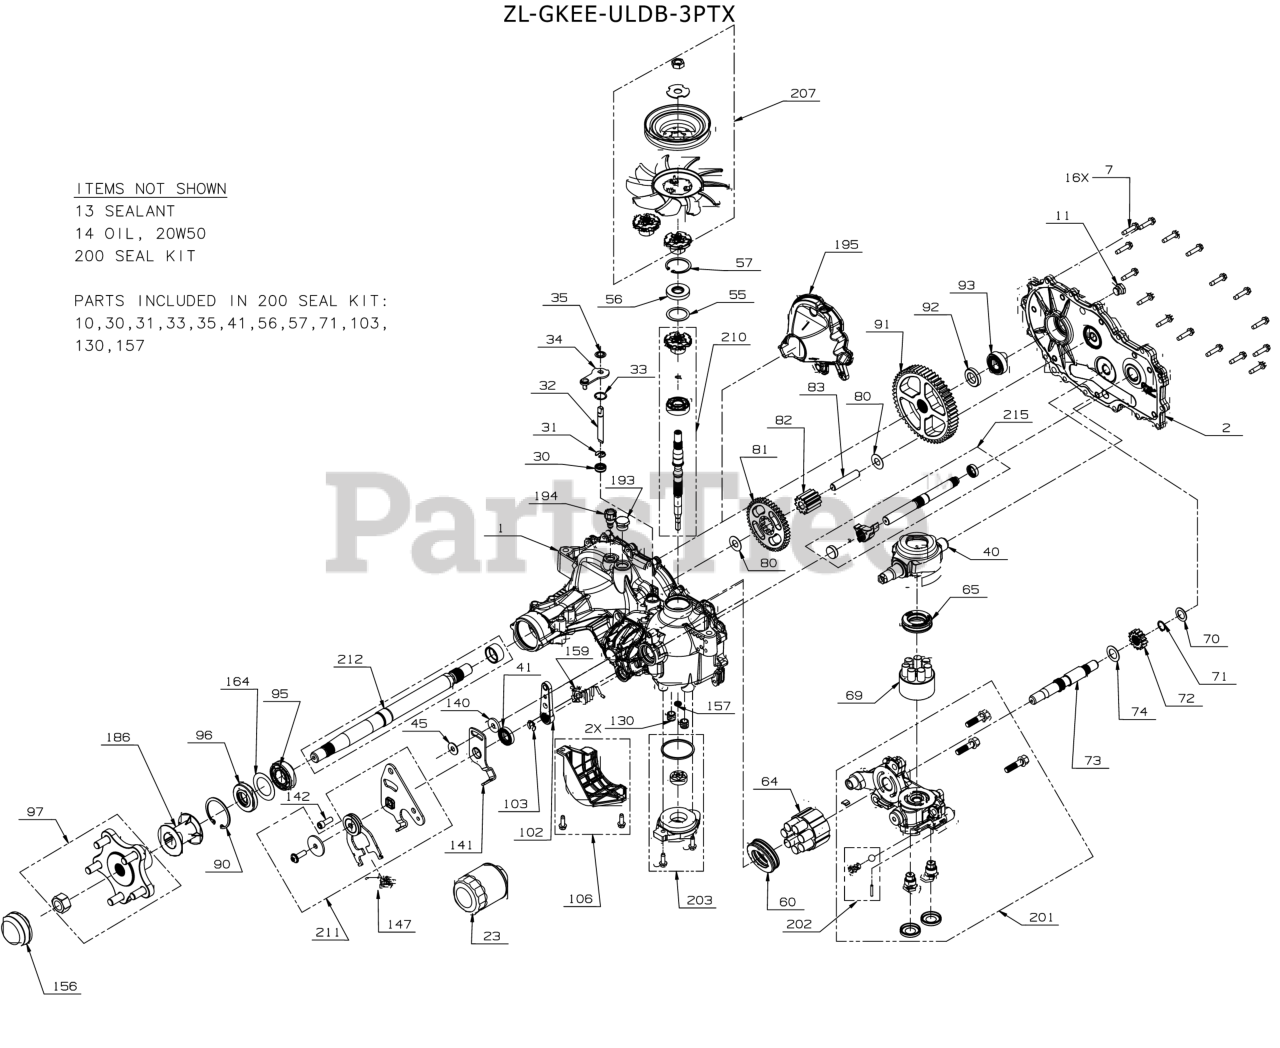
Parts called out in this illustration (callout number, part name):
1	MAIN HOUSING KIT (RH)
2	SIDE COVER KIT (RH)
7	SCREW-WASHER HEAD
11	VENT PLUG
13	SEALANT-HOUSING
23	OIL FILTER
30	SEAL-LIP .375 X .75 X .25
31	RETAINING RING
32	BYPASS RODS
33	RETAINING RING
34	ARM-BYPASS
35	RETAINING RING
40	SWASHPLATE-TRUNNION
45	FLAT WASHER
55	WASHER 1.23X1.56X
57	RETAINING RING
60	THRUST BEARING
64	CYLINDER BLOCK ASSEMBLY
65	THRUST BEARING
69	BLOCK KIT-7 PISTON
70	FLAT WASHER
71	RETAINING RING
73	MOTOR SHAFT
74	MOTOR SHAFT WASHER
81	GEAR-45T JACK SHAF
82	GEAR-11 T
83	PIN-JACKSHAFT
90	RETAINING RING
91	GEAR-54 T
92	SPACER .75X1.32X.257
93	BALL BEARING
95	BALL BEARING
97	5 BOLT HUB KIT
102	BRAKE LEVER
103	RETAINING RING
106	FILTER GUARD KIT
130	TUBE-CHARGE TRIPLE O-RING
140	SPACER .32 x 1.005 x .179
141	ARM-NEUTRAL (RH)
142	SCREWS KIT-RTN
147	EXTENSION SPRING
156	COVER-NUT
157	KIT-GEROTOR SEAL
159	TORSION SPRING CCW
186	TUBE-AXLE 2.03
193	PLUG 3/4-16
194	BREATHER
195	EXPANSION TANK (RH)
201	CENTER SECTION KIT (RH)
202	KIT-CHARGE RELIEF
203	CHARGE KIT
207	FAN & PULLEY KIT
209	PULLER KIT-HUB
210	INPUT SHAFT KIT
211	RETURN KIT-NEUTRAL (RH) ZT2800 RZT
212	SHAFT KIT-AXLE
215	OUTPUT SHAFT KIT
